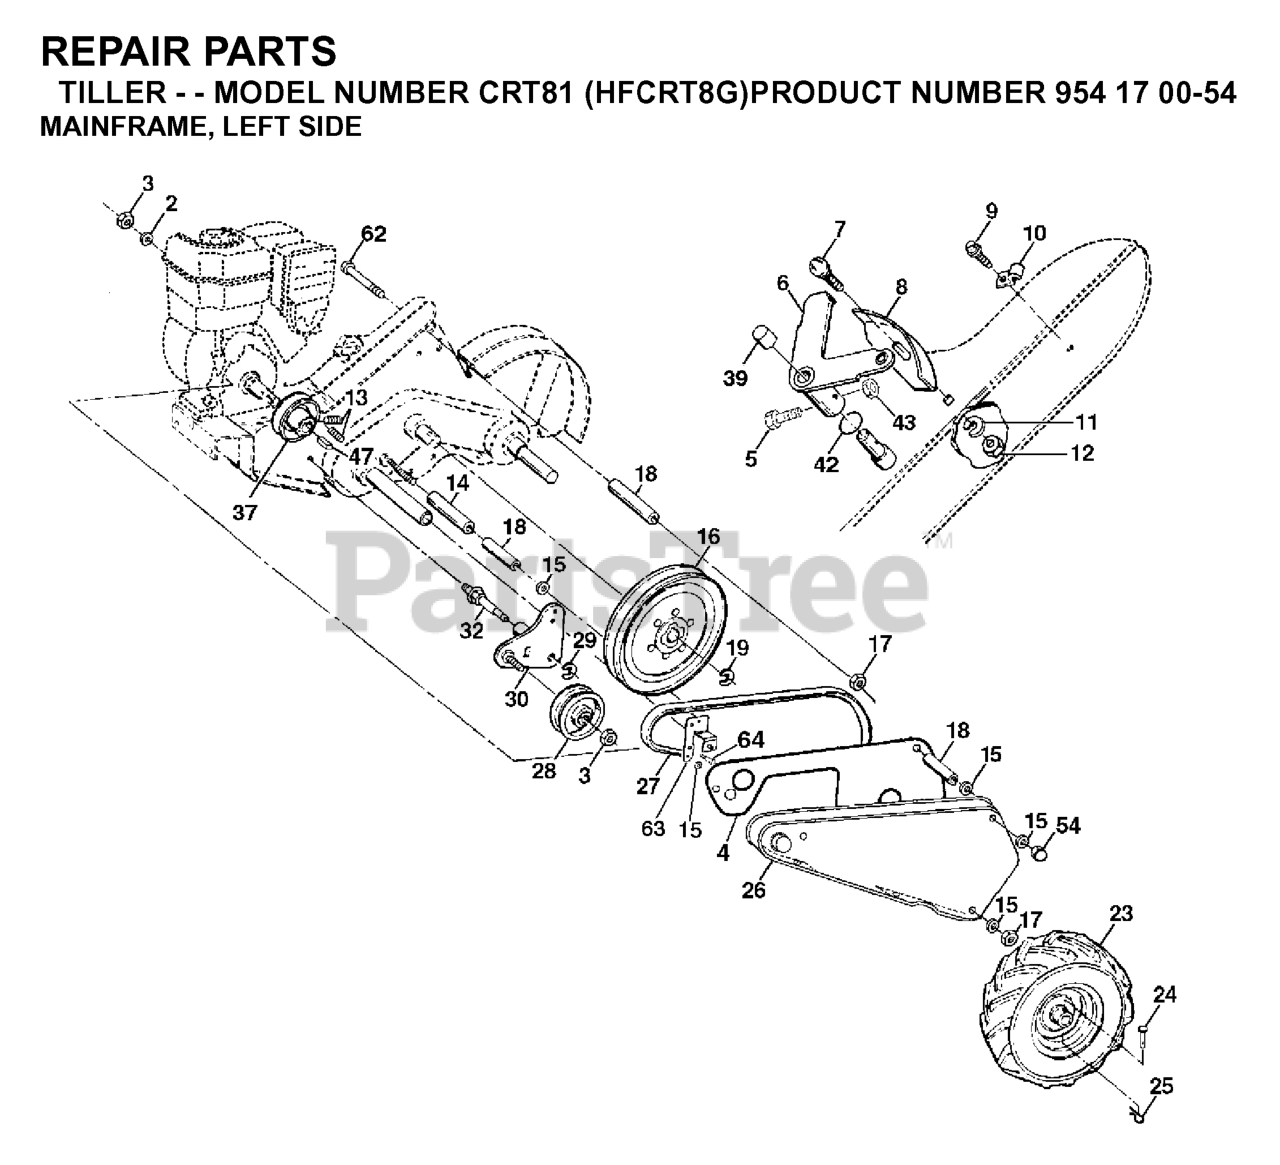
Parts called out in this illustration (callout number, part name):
2	WASHER, LOCK 3/8
3	NUT.HEX.3/8-16UNC
4	Shield, Inner Belt Guard RT
5	SCREW, SHIFT LEVER
6	LEVER ASM CRT
8	PANEL.INDICATOR.SHIFT.BLACK
9	TAPPING SCREW
10	CONDUIT.CLIP.PLATED
11	LOCKWASHER
12	NUT
14	SPACER-SPLIT.327 X .42
15	WASHER
16	SHEAVE, TRANSMISSION
18	SPACER SPLIT
19	RETAINING RING LT
23	TIRE.16X4-8.CHEVRON.TILLER
24	RIVET,DRILLED
25	SPRING TI
26	FOOTREST.PNT.LH
27	BELT, DRIVE
28	PULLEY-IDLER TI
30	BRACKET.ASM.IDLER.BLACK
32	SHAFT, IDLER ARM
37	SHEAVE, ENGINE
39	CAP.PLUNGER.BLACK
47	KEY, SQUARE
62	BOLT 5/16-18X4 1/2
63	Bracket Asm Guard
